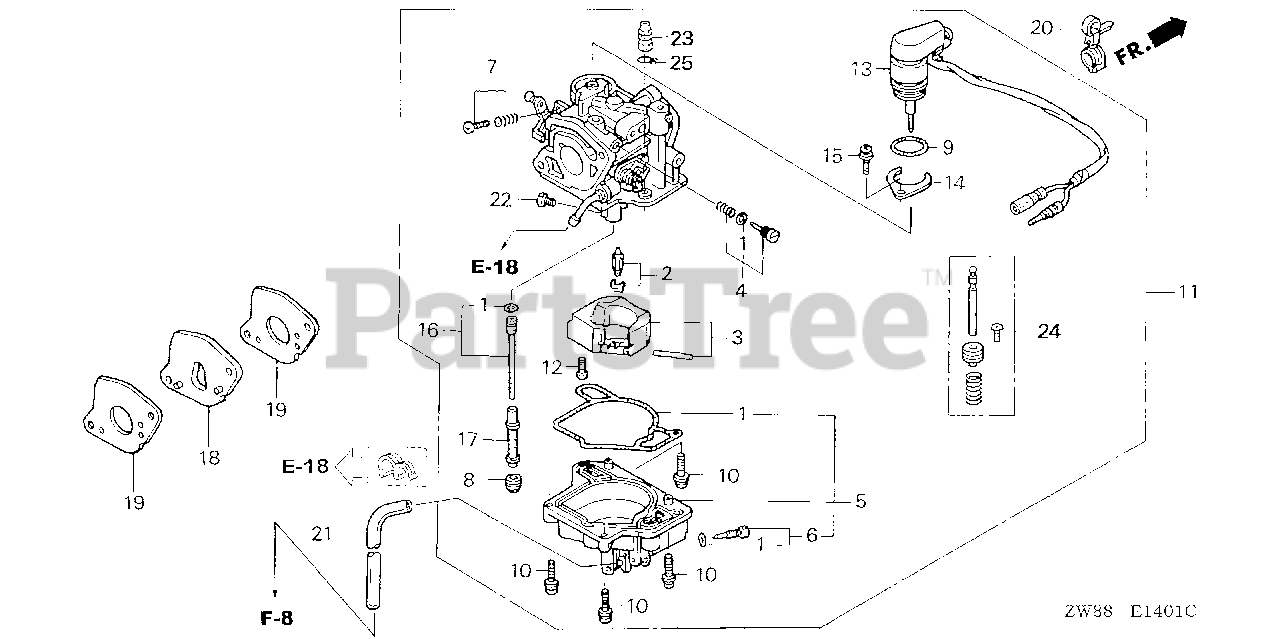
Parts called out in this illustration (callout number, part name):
1	GASKET SET
2	VALVE SET, FLOAT
5	CHAMBER SET, FLOAT
6	SCREW SET, DRAIN
8	SCREW, PLUG
9	O-RING, BYSTARTER
10	SCREW-WASHER
11	CARBURETOR ASSY. (BJ05B D)
12	SCREW, PAN
13	BYSTARTER ASSY., AUTO
14	PLATE, SETTING
15	SCREW-WASHER
16	JET SET (#45)
17	NOZZLE, MAIN
18	INSULATOR, CARBURETOR
19	GASKET, CARBURETOR
20	CLIP, TUBE (135MM) (BLACK)
21	BULK HOSE, VINYL (4X7X8000) (4X7X200)
22	JET, MAIN (#100)
22	JET, MAIN (#102)
22	JET, MAIN (#105)
24	PLUNGER SET, ACCELERATOR PUMP
25	CLIP, TUBE
